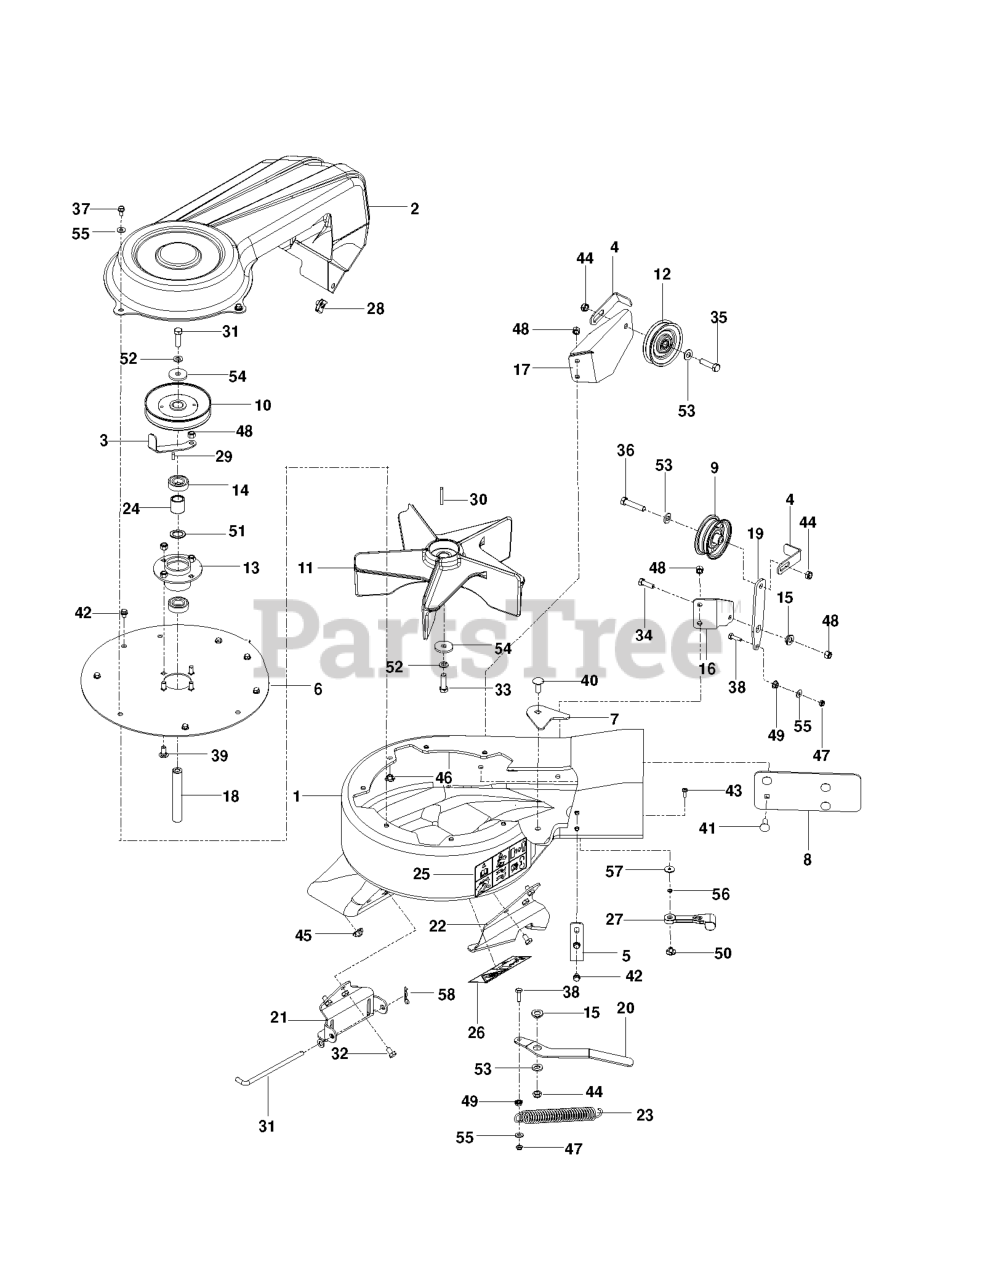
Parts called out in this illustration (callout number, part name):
1	BLOWER.HOUSING.W/DECALS.COLLEC
2	COVER, BELT
3	KEEPER, BELT, OUTER
4	KEEPER, BELT, REAR
6	PLATE, OUTER
7	PLATE, BACKING
8	PLATE.BACKING.BLACK
9	IDLER PULLEY
11	IMPELLER.COLLECTION.BLOWER.BLA
13	HUB, BEARING
16	MOUNT, IDLER, UPPER
17	MOUNT, IDLER, LOWER
18	SHAFT, IMPELLER
19	ARM, IDLER
20	ARM, TENSION
21	BRKT, MT, FRONT
22	BRKT, MT, REAR
25	DECAL, EURO WARNING
26	EURO DECAL, IMPELLER
27	HOOD LATCH
28	U-CLIP 5/16-18 NUT RETAINER
29	KEY, 3/16 X 1/2
30	KEY-SQ. 3/16 X 1 1/2
31	PIN, RETENTION
32	HCS 5/16-18 X 1/2 GR 5 ZD
33	BOLT - 5/16 X 7
34	HCS 5/16C X 1
35	HCS 3/8C X 1 1/2
36	BOLT, HCS 3/8-16X1-3/4
37	BOLT 1/4-20 X 1/2 HWST
38	HCS 1/4-20X7/8 GR5
39	BOLT 5/16C X 3/4" CARRIAGE
40	RHSNB 3/8C X 1
41	RHSNB 5/16C X 1
42	HWST 1/4C X 3/8
43	SCREW #10-24 X 5/8
44	NUT HEX 3/8-16 NYLON, THIN
45	NUT 5/16-18 TEE
46	NUT 1/4-20 TEE
47	JAM NUT 1/4C (2 2 PW01)
48	NUT 5/16 NYLOC
49	NUT 1/4-20 HEX FLG LK ZD
50	NUT 10-24 WELD PLATED
51	WASHER .787 X 1.125 X .06
52	SLW 3/8 STD
53	WASHER 3/8 SAE FLAT
54	FLAT WASHER 5/16 SAE
55	WASHER 1/4 SAE
56	WASHER - 3/16 LOCK ZD
58	WASHER, HARDENED
